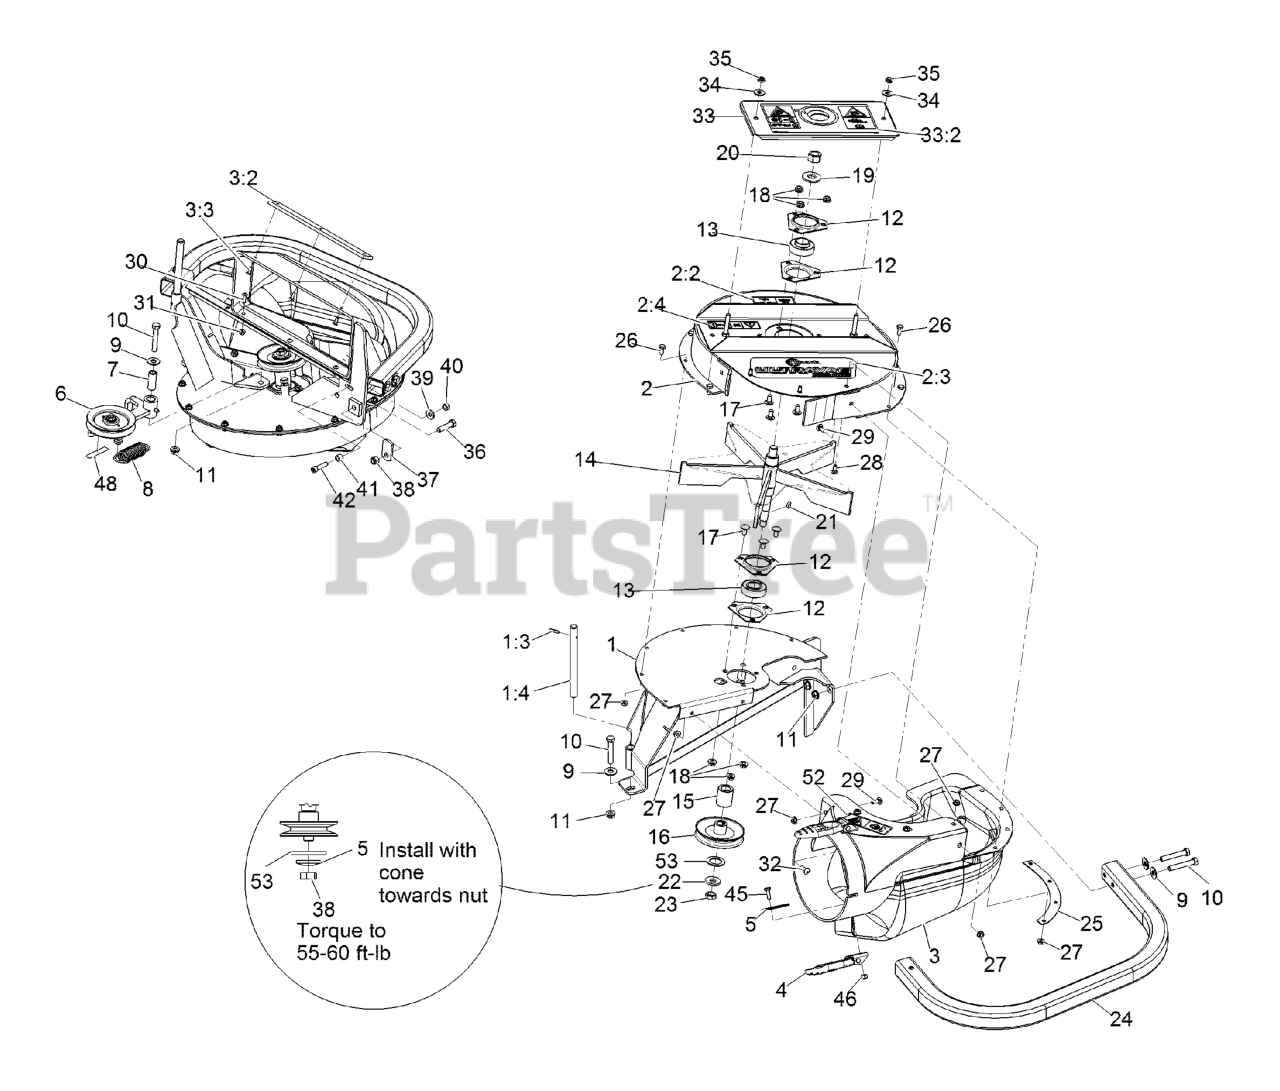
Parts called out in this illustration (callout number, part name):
1	WLD,FRAME LG BLOWER
1:3	PIN-ROLL
1:4	SHAFT-CATCHER, GRASS
2	ASM-UPPER HOUSING LARGE
2:2	DECAL-WARNING, TRACTION
2:3	DECAL-ULTRAVAC X-SERIES
2:4	DECAL-COVER, MISSING
3	ASM,BLOWER CHUTE LZ
3:2	PLATE,REINFORCEMENT LARGE
3:3	RIVET-BLIND
4	LATCH-RUBBER
5	PLATE-BACKING
6	ASM, Idler
7	BUSHING
8	SPRING-IDLER
9	WASHER-FLAT
10	SCREW-HH
11	NUT-HHF, WHIZ
12	HOUSING-FLANGE
13	BEARING
14	IMPELLER
16	SHEAVE
17	SCREW-CARR
19	WASHER-SPRING
20	NUT-HEX
21	KEY-WOODRUFF
22	WASHER-SPRING
23	NUT-JAM
25	PLATE-BACKING, BLOWER
26	SCREW-HH
28	SCREW-CARR
29	BOLT-CARR
30	SCREW-HEAD, TRUSS
33	ASM, BEARING COVER
33	COVER, BEARING
33:2	DECAL-WARNING, BLOWER
34	WASHER-FLAT
35	NUT-LOCK, NI
36	SCREW-HH
37	LATCH-CATCHER, GRASS
38	NUT-LOCK, NI
39	WASHER-SPRING
40	NUT-HEX
41	BUSHING, LOCATOR
42	SCREW-HSH
45	SCREW-HH
46	NUT-LOCK, NI
48	DECAL-WARNING
52	Decal-Blower-Impeller Hazard
53	WASHER-SPACER
